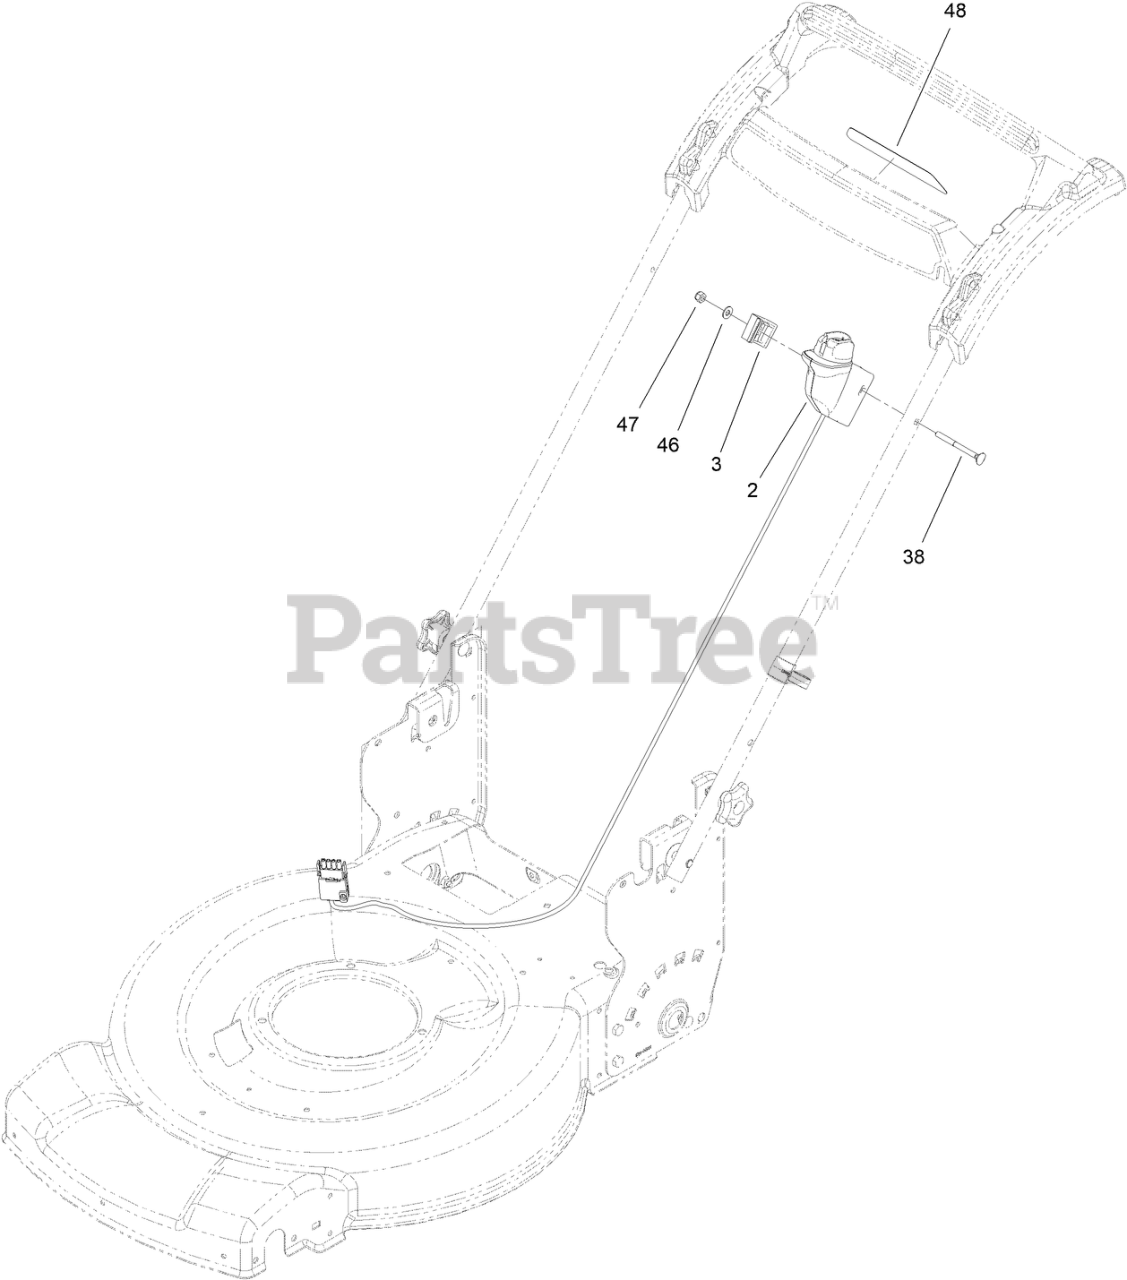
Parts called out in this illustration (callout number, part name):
2	SWITCH-STARTER ASM
3	CLAMP-CABLE
38	SCREW-HANDLE
46	WASHER-FLAT
47	NUT-LOCK, NI
48	DECAL-CONTROLS (60V, START)
